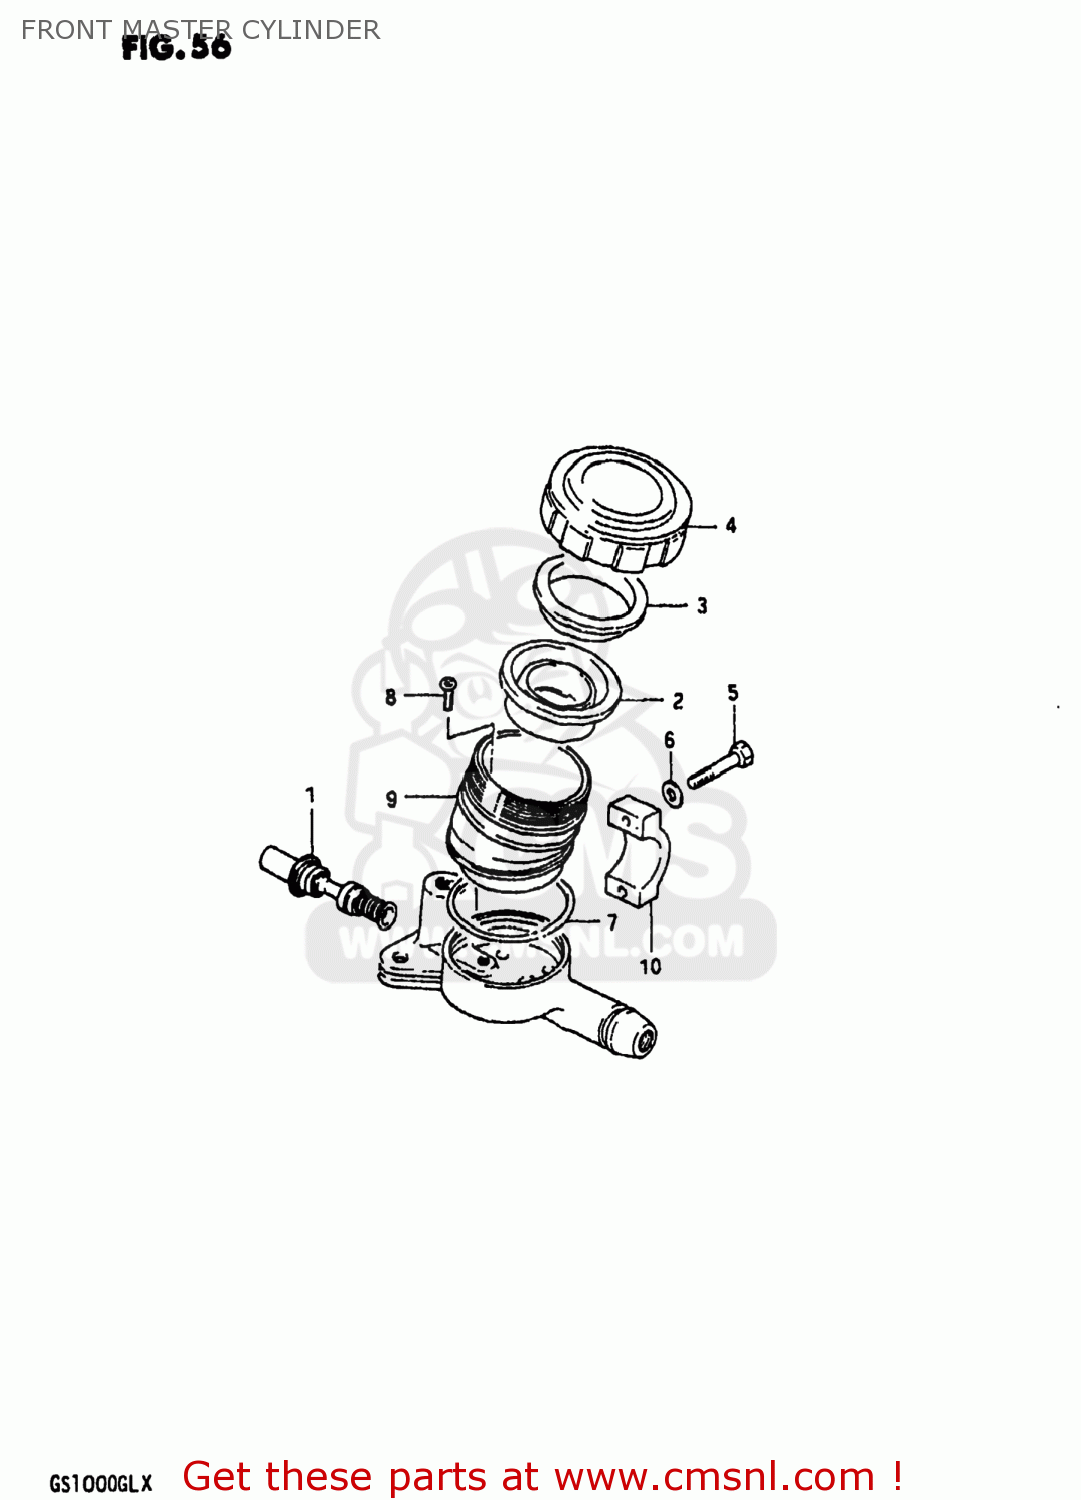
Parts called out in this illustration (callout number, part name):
1	PISTON & CUP SET
2	DIAPHRAGM
3	PLATE,DIAPHRAGM
4	CAP
5	BOLT
6	WASHER
7	O RING
8	SCREW,MASTER CYLINDER
9	RESERVOIR
10	HOLDER,MASTER CYLINDER
